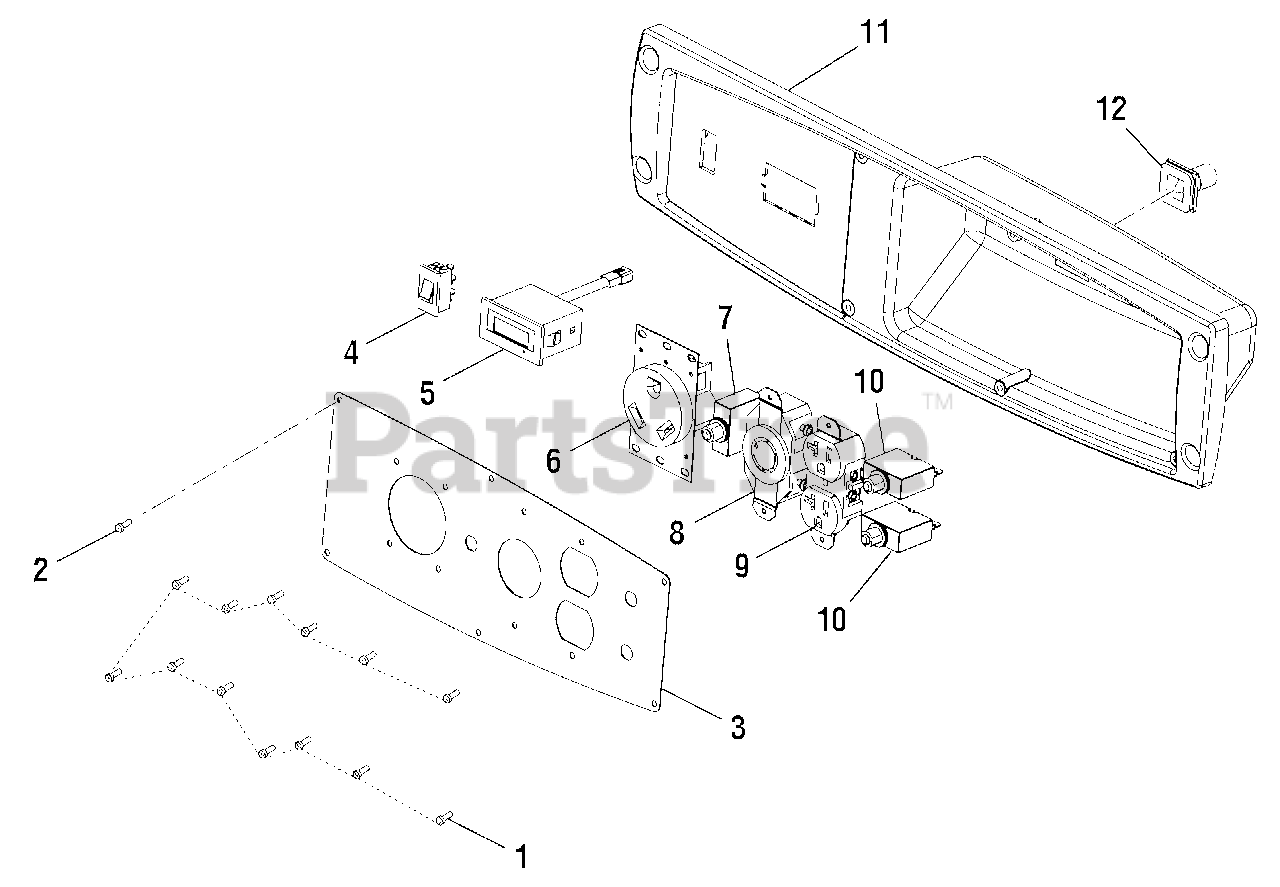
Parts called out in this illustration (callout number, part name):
1	Screw (#6-20 x 9.65 mm)
2	Screw (#6-20 x 20 mm)
3	Electrical Panel
5	Digital Display
6	120V/30A Recepticle (RV)
7	30A Circuit Breaker
8	120V/30A Recepticle (Twist Lock)
9	120V Duplex Receptacle
10	20A Circuit Breaker
11	Front Panel Assembly
12	Rubber Boot
